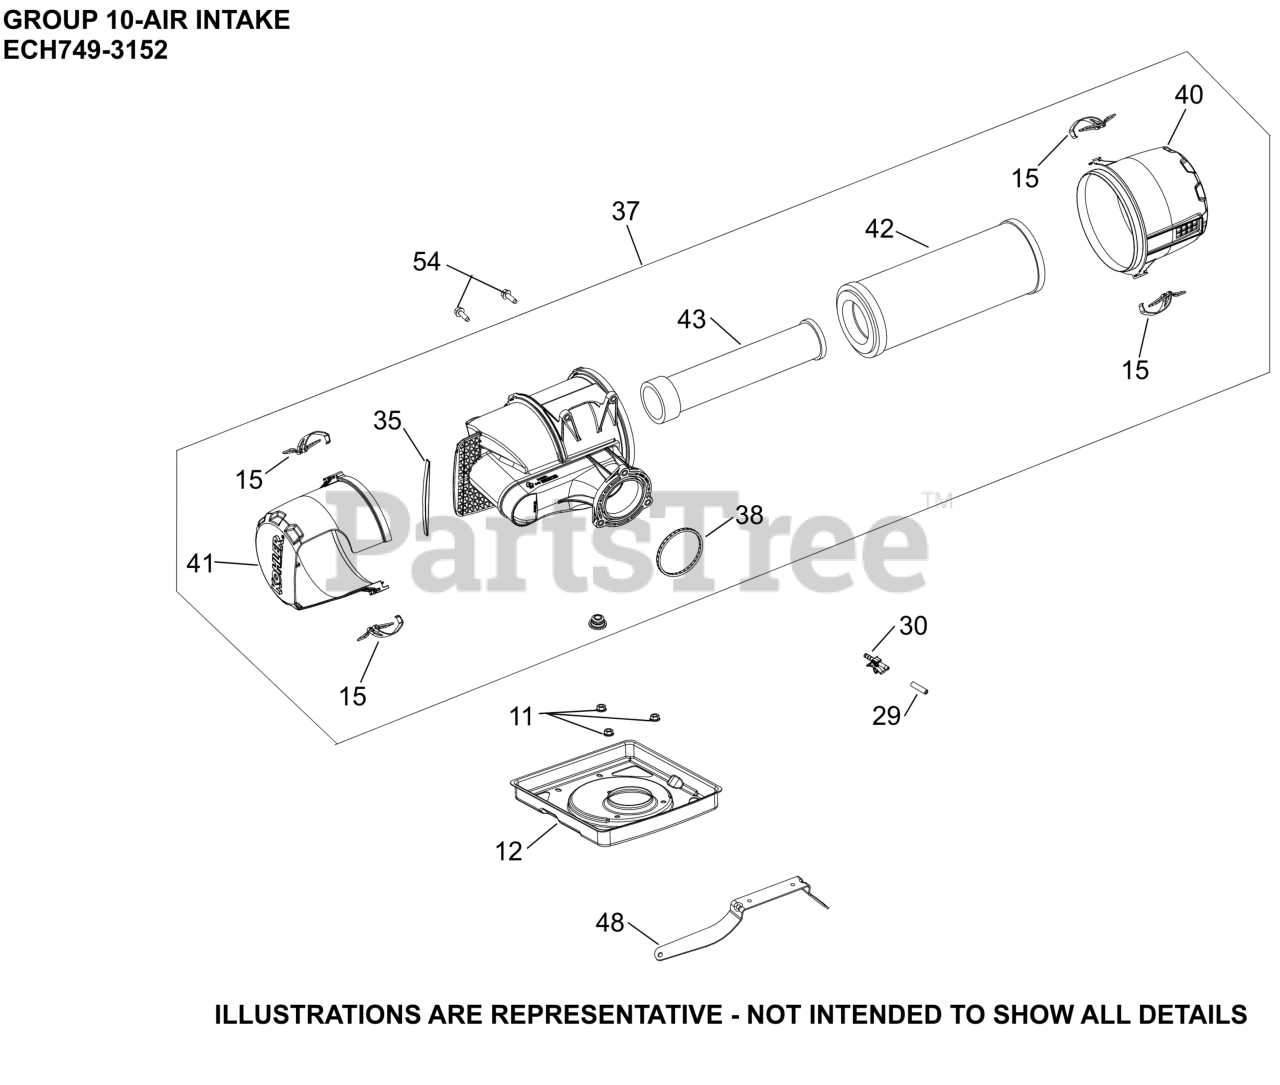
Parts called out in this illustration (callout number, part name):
11	NUT, FLG M6X1.0
12	BASE, AIR CLEANER
15	CLIP ASSEMBLY
29	CAP, MASKING
30	CONNECTOR, EVAPORATIVE
35	DAMPER, FOAM INSERT
37	FILTER, AIR ASSY W/BREATHER HOLE
38	O-RING (HDAC SEAL-EFI)
40	COVER, AIR FILTER
41	COVER, RAIN CAP
42	ELEMENT, AIR FILTER - PRIMARY
43	ELEMENT, AIR FILTER - SAFETY
48	AIR CLEANER BRACKET
54	SCREW, THREAD FORMING
